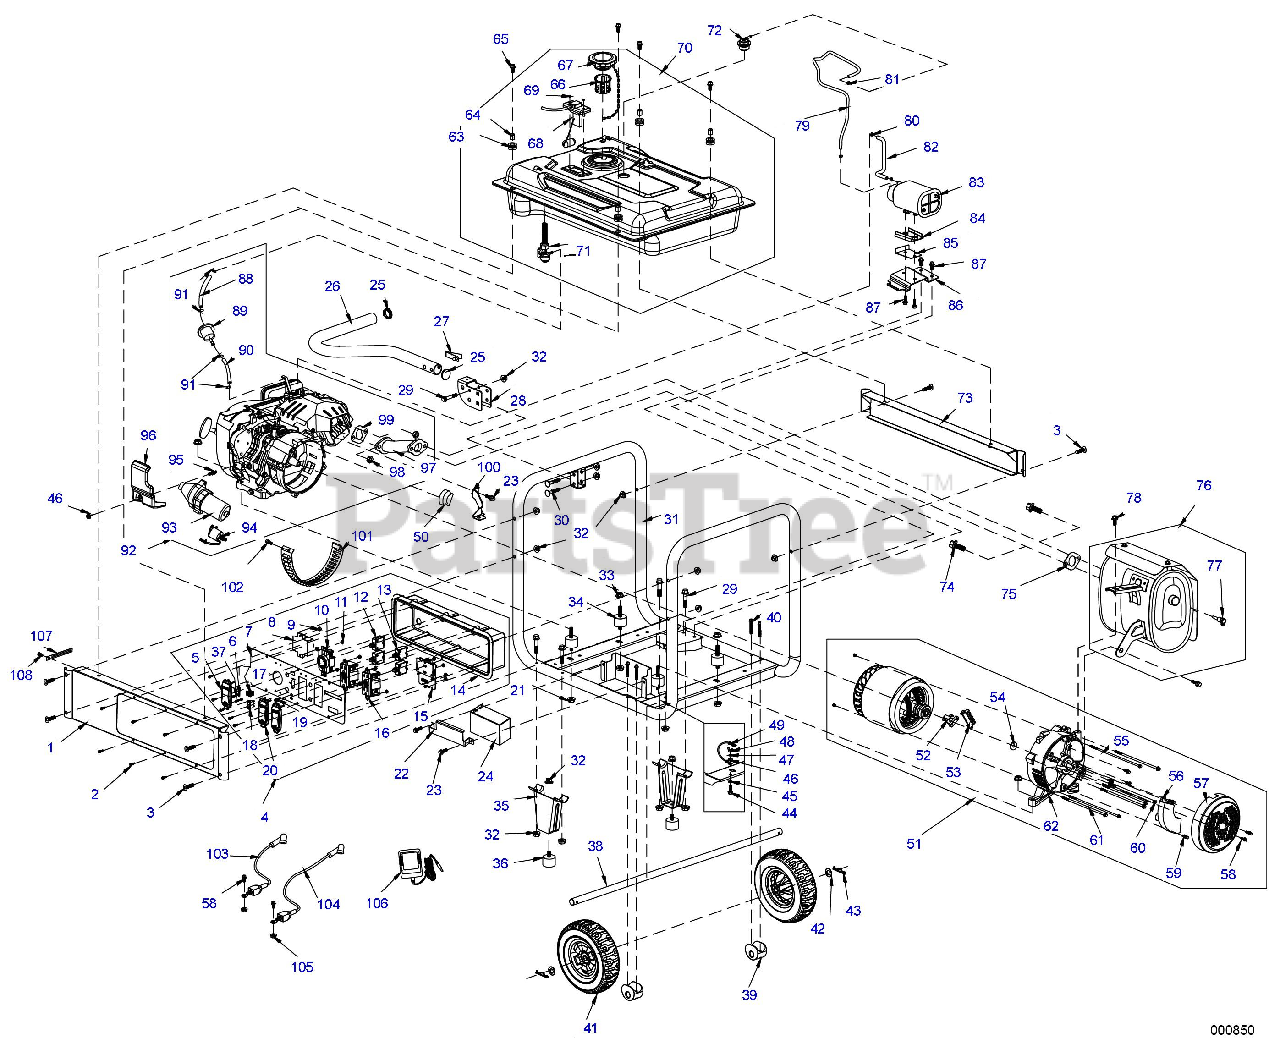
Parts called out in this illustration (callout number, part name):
1	FRAME RAIL (MATTE YELLOW)
2	PAN HEAD SCREW (ST4x16)
3	CURVED HEAD BOLT (M8X40)
4	CONTROL PANEL ASSEMBLY
5	OUTLET COVER
6	NUT (M3)
7	CONTROL PANEL FACE PLATE WELDMENT
8	IDLE SPEED CONTROLLER
9	NUT (M5)
10	RECEPTACLE
12	CIRCUIT BREAKER (30A)
13	CIRCUIT BREAKER (20A)
14	CONTROL PANEL BACK COVER
15	POWERBAR Y20 ASSEMBLY
16	RECEPTACLE (GFCI)
17	IDLE SPEED SWITCH
18	ENGINE ON/OFF SWITCH
19	BATTERY CHARGER SOCKET
20	OUTLET COVER
22	BATTERY COMPARTMENT COVER
23	BOLT (M6X12)
24	BATTERY
25	HANDLE PLUG
27	SNAP BUTTON
28	HANDLE BRACKET
29	BOLT (M8X45)
30	CARRIAGE HEAD BOLT (M8X46)
31	FRAME
32	NUT (M8)
33	NUT (M10)
34	RUBBER VIBRATION MOUNT
35	BENT FOOT FRAME
36	RUBBER FOOT
37	SOCKET HEAD CAP SCREW (M3X10)
38	AXLE PIN
39	FIXED AXLE BLOCK
40	BOLT (M6X50)
41	WHEEL ASSEMBLY
42	FLAT WASHER
43	COTTER PIN
44	BOLT (M6X20)
45	SPECIAL LOCK WASHER
47	FLAT WASHER
48	NUT (M6)
49	GROUND WIRE ASSEMBLY
51	ROTOR AND STATOR ASSEMBLY
52	BRUSH ASSEMBLY
53	WIRE CONNECTION TERMINAL
54	FLAT WASHER (M10X4)
55	STATOR BOLT (M5X204)
56	AUTOMATIC VOLTAGE REGULATOR
57	GENERATOR END COVER
58	BOLT (M5X12)
59	BOLT (M5X16)
60	ROTOR BOLT (M10X255)
61	STATOR BOLT (M6X165)
62	REAR BEARING HOUSING
63	FUEL TANK RUBBER MOUNT
64	ANTI-CRUSH LINING INSERT
65	BOLT (M8X20)
66	FUEL FILTER
67	FUEL CAP
68	FUEL SENSOR
69	CROSS HEAD SCREW (M5X13)
70	FUEL TANK (7.5 GALLON)
71	FUEL SHUT OFF VALVE
72	ROLL OVER VALVE
73	FRAME BACK RAIL (MATTE YELLOW)
74	BOLT (M8X25)
75	MUFFLER EXHAUST GASKET
76	MUFFLER
77	SPARK ARRESTOR
78	BOLT (M8X16)
79	HOSE (CARBON CANISTER TO ROLL OVER VALVE)
80	HOSE CLAMP
81	HOSE CLAMP
82	HOSE(CARBON CANISTER TO AIR BOX)
83	CARBON CANISTER (682CC)
84	CANISTER BRACKET
85	LIMIT BOARD
86	CANISTER BRACKET
87	BOLT (M6X12)
88	FUEL HOSE (09.6X65)
89	FUEL FILTER
90	FUEL HOSE (09.6X80)
91	HOSE CLAMP
92	ENGINE 420 CC
93	STARTER MOTOR
94	STARTER RELAY
95	TWO HEADED BOLT
96	SENSOR COVER
97	EXHAUST MANIFOLD
99	CYLINDER EXHAUST GASKET
100	AIR CLEANER BRACKET
101	ALTERNATOR SCROLL
102	BOLT (M5X10)
103	BATTERY CABLE (POSITIVE-RED)
104	BATTERY CABLE (NEGATIVE -GREEN OR BLACK)
105	NUT (M5)
106	BATTERY CHARGE R
107	CABLE CLEAT
108	PAN HEAD SCREW (M5X10)
109	CO WARNING DECAL
110	WARNING DECAL
